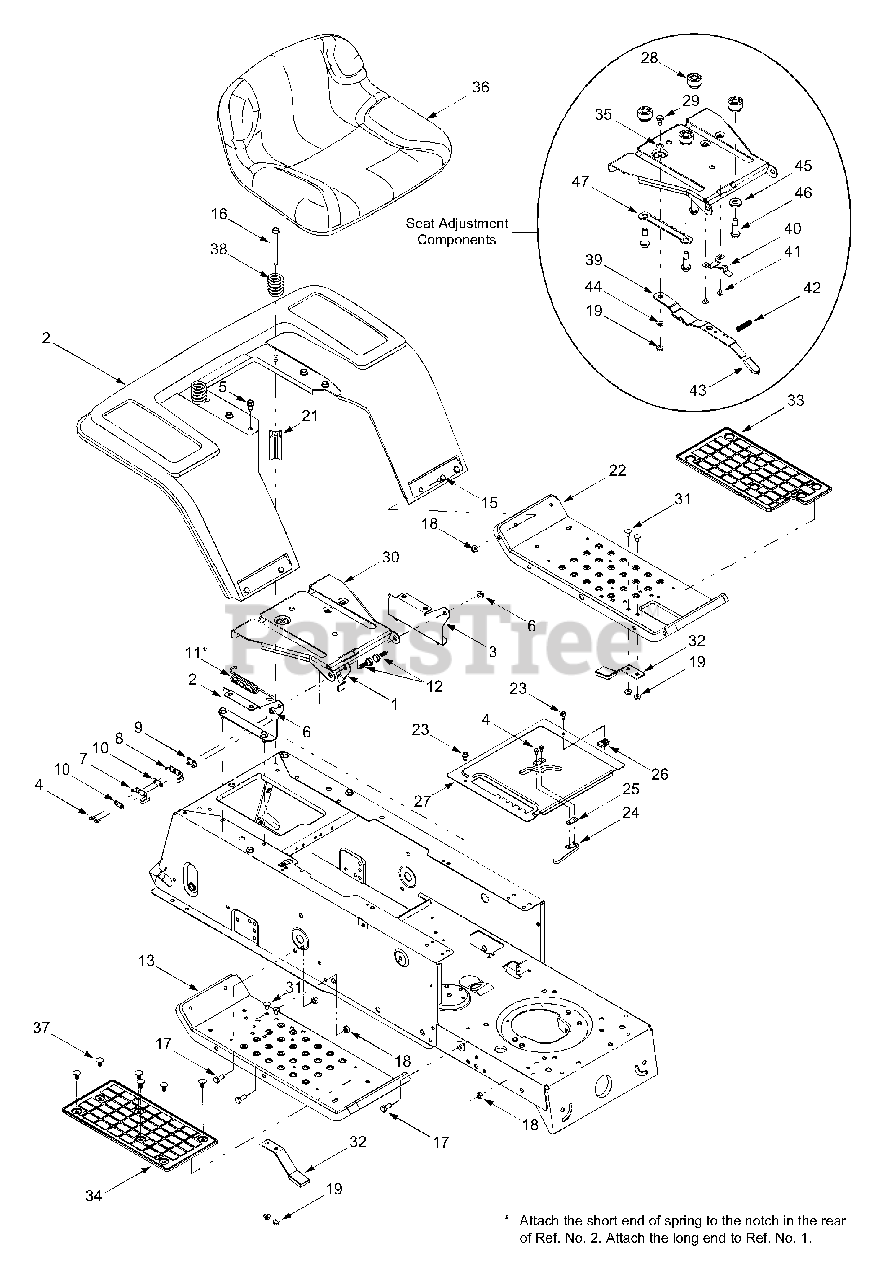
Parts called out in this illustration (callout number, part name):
1	Seat Lift Bracket
4	Self-tapping Screw, #8-18 x .50
5	Self-tapping Screw, 5/16-12 x .75
6	Flange Lock Nut, 5/16-18
7	Outer Seat Spring Switch
8	Inner Seat Spring Switch
9	Insulator Plate Boss
10	Insulator Plate
11	Extension Spring, .75 x 5.31
12	Shoulder Screw, .437 x .286
16	Self-tapping Screw, 5/16-18 x 3.5
17	Hex Screw, 5/16-18 x .75
18	Nylon Lock Nut, 5/16-18
19	Flange Lock Nut, 1/4-20
24	Spring Switch, Long
25	Insulator Nut Plate
26	U-Clip Nut, 1/4-20
29	Shoulder Screw, .340 x .285, 1/4- 20
32	Blade Spindle Brake Assembly
33	LH Rubber Foot Pad
34	RH Rubber Foot Pad
35	Flat Washer, .344 x .62
36	Low Back Seat, Black
37	Ratchet Clip, .250 Dia
38	Compression Spring, 1.314 x 2.55
39	Seat Adjustment Lever
41	Screw, #10-16 x .375
42	Compression Spring
44	Spring Washer
45	Flat Washer, .531 x 1.062 x .134
46	Shoulder Screw, .50 x .925, 3/8-16
47	Seat Select Bracket
